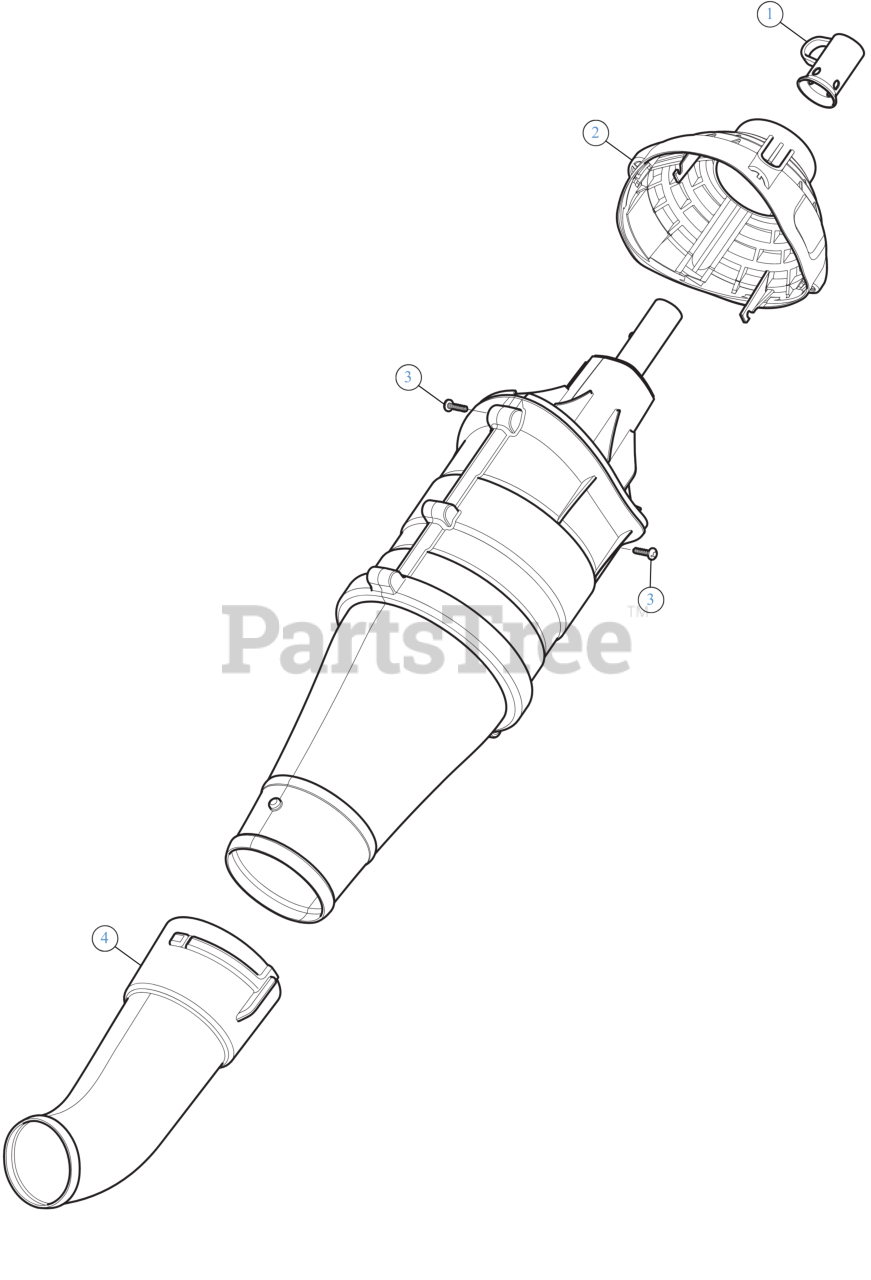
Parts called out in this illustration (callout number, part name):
1	HANGER
2	BLOWER INTAKE COVER
3	SCREW 8-16 x 3/4
4	NOZZLE BLOWER ATACH
